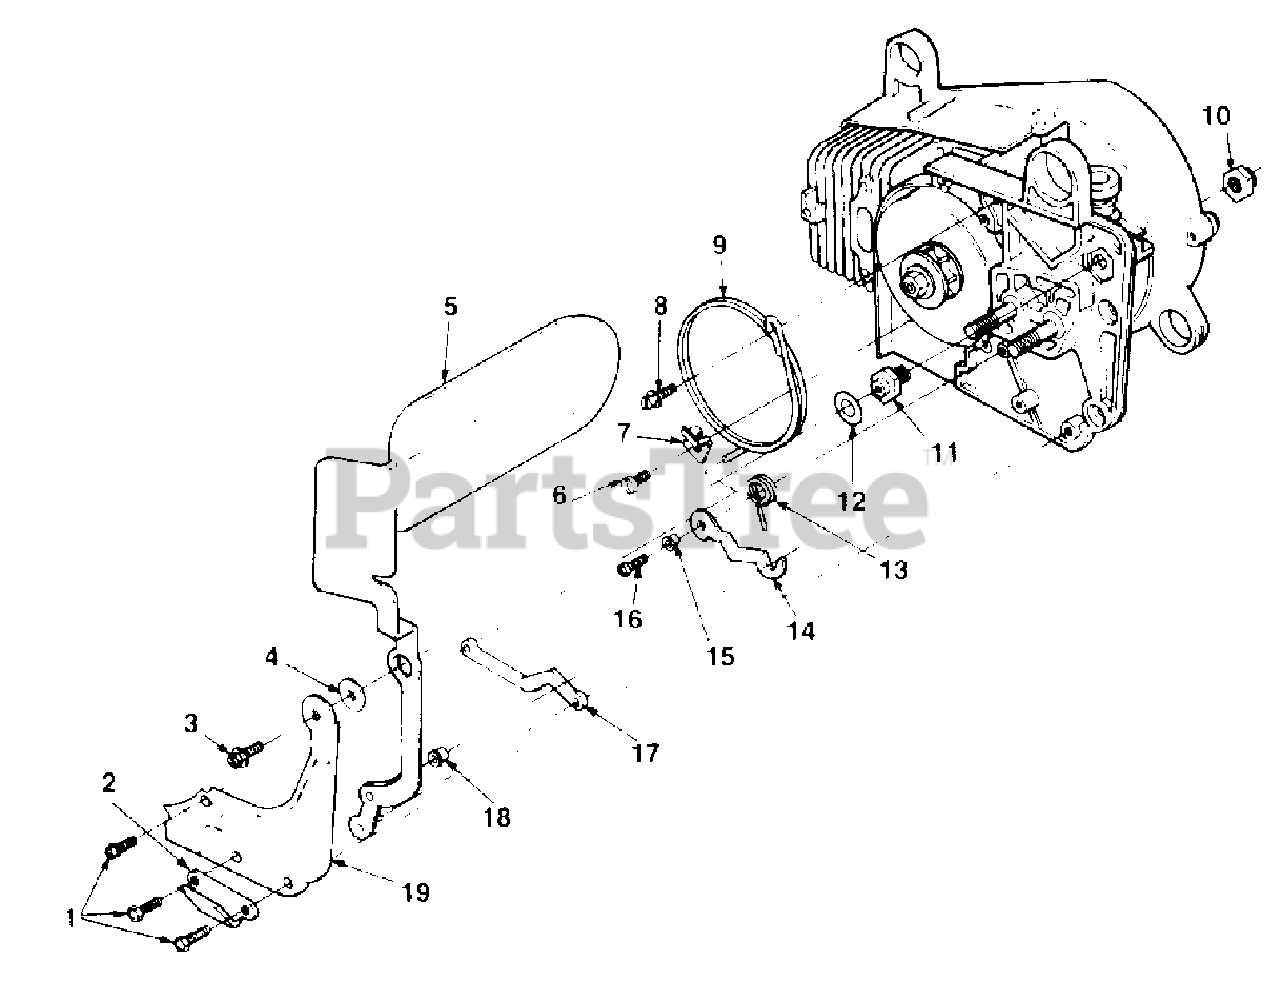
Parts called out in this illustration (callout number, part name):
1	SCREW- (8-32 x 1/2)
2	STOP- Chain
3	SCREW- (10-24 x 3/8)
4	WASHER- Flat
5	GUARD- hand
6	SCREW- Pan hd
7	BRACKET
8	SCREW (12 24 x 1/2)
9	BAND- Brake
10	NUT- Hex (3/8-24)
11	INSERT- Chain brake
12	WASHER- Spring
13	SPRING- Torsion
14	DETENT- Brake lever
15	SPACER- Flanged
16	SCREW- Mach pan hd. (8-32 x 1/2)
17	LINK- Chain brake
18	BUSHING
19	SHIELD- Chain brake
